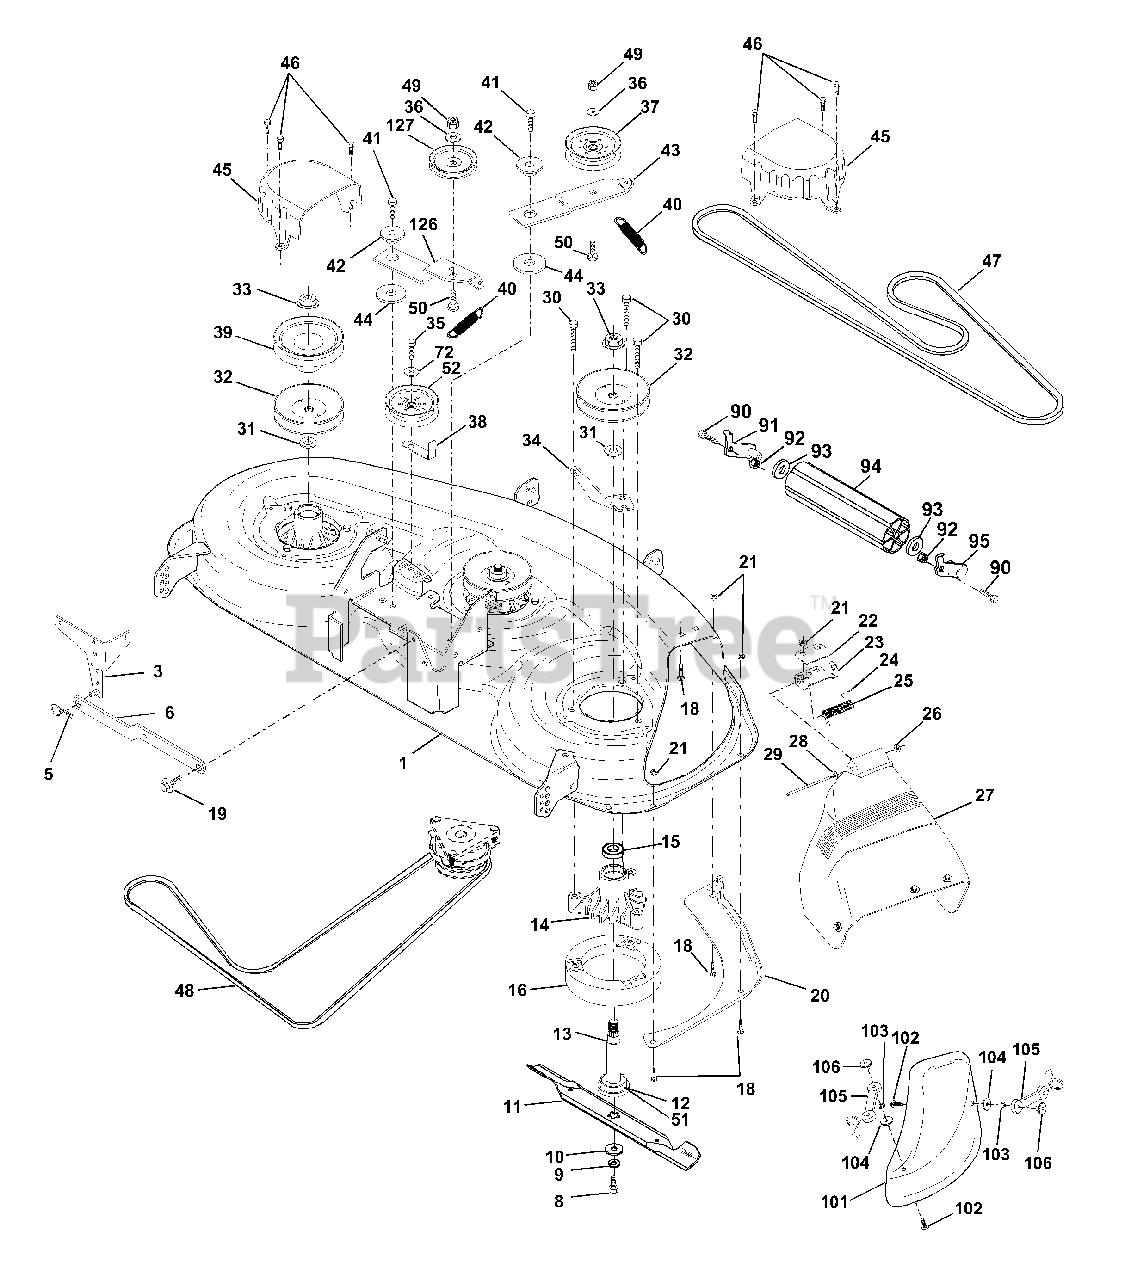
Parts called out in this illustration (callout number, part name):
1	Deck Asm., Mower 46"
3	Bracket Asm., Sway Bar
5	Retainer Spring
6	Arm, Suspension, Rear (Sway Bar)
8	Bolt, Patched 3/8-24 x 1-1/4 Gr. 8
9	Washer, Lock Hvy., Unplated 3/8
10	Washer, Hard Blade, Mower Vented
11	Blade, High Performance
11	Blade, Mulching
12	Bearing, Ball, Mandrel #6204
13	Shaft Asm. w/Lower Bearing
14	Housing, Mandrel
15	Bearing, Ball, Mandrel
16	Stripper, Mower Round
18	Bolt, Carriage 5/16-18 x 5/8
19	Bolt, Shoulder 5/16-18
20	Baffle, Vortex Mower 46"
21	Nut, Crownlock 5/16-18 UNC
22	Stiffiner, Bracket
23	Bracket, Deflector
24	Cap, Sleeve
25	Spring, Torsion, Deflector
27	Deflector Clipping 46" Grey
28	Washer 11/32 x 5/8 x 16 Ga.
29	Rod, Hinge
30	Screw, Thdroll Washer Head
31	Washer, Spacer Mower Vented
32	Pulley, Mandrel
33	Nut, Flg. Top Lock Cntr. 9/16
34	Anchor, Spring Deck 46"
35	Screw thdroll 3/8-16 x 1-3/4 Tytt
36	Washer 13/32 x 13/16 x 16 Ga.
37	Pulley, Idler, Flat
38	Keeper, Belt, Idler
39	Pulley, Idler, Driven
40	Spring, Secondary 44/46/50 Vent
41	Screw, 3/8-16 x 1-1/4 Smgml Tap/R
42	Spacer, Retainer, Mower
43	Arm, Idler Secondary
44	Washer, Hardened
45	Cover, Mandrel Deck
46	Screw, Thdroll. 1/4-20 x 5/8
47	V-Belt, Mower, Secondary
48	V-Belt, Mower, Primary
49	Nut, Crownlock 3/8-16 UNC
50	Bolt, Carriage 3/8-16 x 1-1/2 Gr. 5
51	Washer Felt
52	Pulley Idler 46 Pri Drive 97
56	Bar Adjusting Guage Wheel
57	Pin Head Rivet
72	Washer 13/32 x 1 x 16 Ga.
90	Bolt, Fin Hex 3/8-16 UNC x 1
91	Bracket Asm. Noseroller, Lh
92	Nut Lock Hex W/Ins. 3/8-16 Unc
93	Washer 17/32 x 7/8 x 16 Ga.
94	Roller Nose 38 & 42
95	Bracket Asm. Noseroller, Rh
101	Cover Mulcher
102	Screw Truss Hd Phil 10-24 x 5/8
103	Washer Lock #10
104	Nut Weld
105	Washer #10
106	Latch Asm Mulch/Bagger
116	Bolt, Shoulder
117	Gauge Wheel
118	Nut, Centerlock 3/8-16 UNC
119	Washer 3/8 x 7/8 x 14 Ga.
126	Arm, Idler, Primary Deck 46"
127	Pulley, Idler, V-Groove Dim. 4.25
